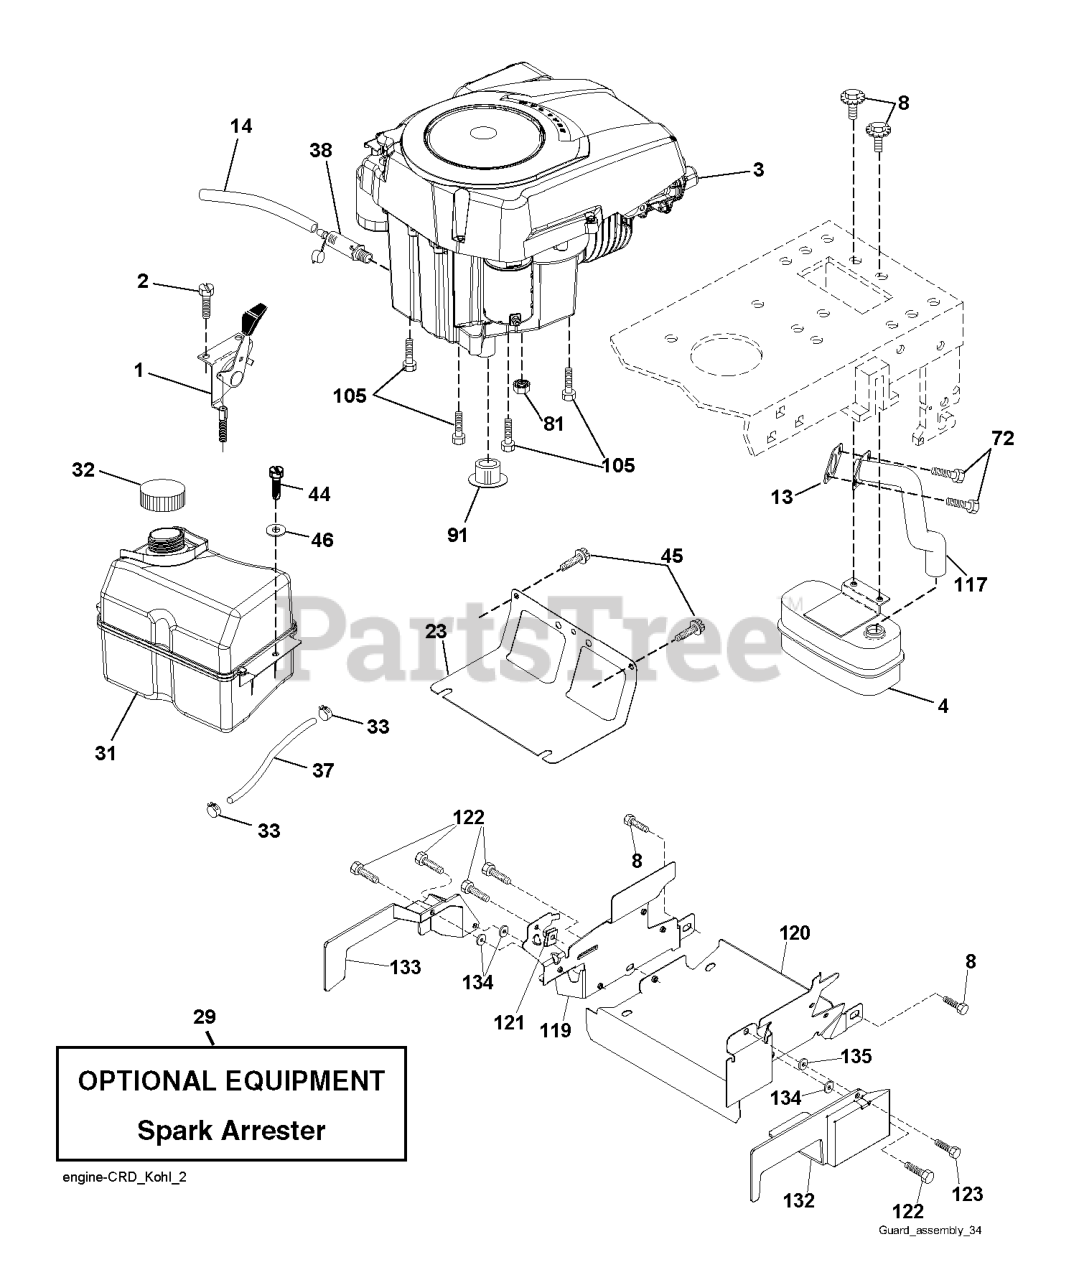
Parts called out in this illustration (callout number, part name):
1	CONTROL.TH/CK.C.
2	SCREW.#10 X 0.750.BOS
4	MUFFLER.SINGLE.CYL.KOHL/B&S
8	BOLT.5/16-18UNCX3/4 W/SEMS.BLK
13	GASKET.EXHAUST.KOHLER
14	TUBE, DRAIN OIL ASM.
23	SHIELD.BROWNING.DBR.GUARD
29	KIT.SPARK ARRESTOR 794945 B&S
31	RP TANK FUEL FRT 1.5 GAL
32	FUEL CAP
33	HOSE CLAMP
37	LINE.FUEL.20
38	PLUG DRAIN OIL EASY
44	SCREW HEXWSHR 1/4-20X3/4
45	SCREW, 3/8-16X3/4
72	SCREW.SOCKET HD.5/16-1
81	NUT
91	BUSHING.1.375OD
105	SCREW 3/8-16X1
117	RP.TUBE.EXHAUST.KOHL.COURAGE
119	LENKRAD
120	GUARD 532199767
122	SCREW.1/4-20X5/8
123	SCREW, 5/16-18 X 1/2
132	SHIELD RIGHT
133	SHIELD LEFT
134	PALNUT 1/4
135	WASHER 5/16"
